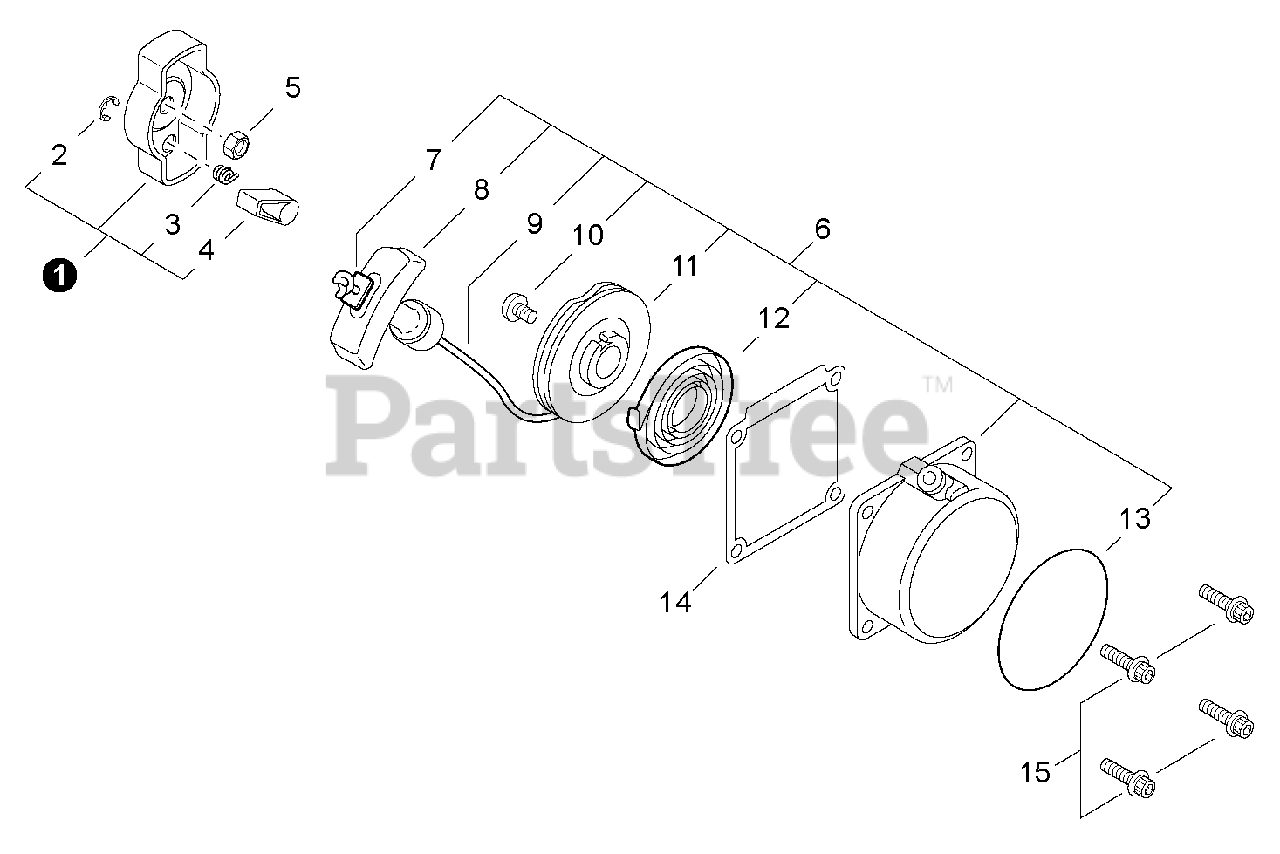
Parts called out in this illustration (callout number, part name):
1	PULLEY ASSY, STARTER
2	E-RING 4
3	SPRING, RETURN
4	PAWL, STARTER
5	NUT 8
6	STARTER ASSY, RECOIL
7	RETAINER, ROPE
8	GRIP, STARTER
9	ROPE, STARTER
10	SCREW 5
11	REEL, ROPE
12	SPRING, RECOIL
13	LABEL, TRADE
14	GASKET, RECOIL STARTER
15	BOLT, ADHESIVE M4×16
